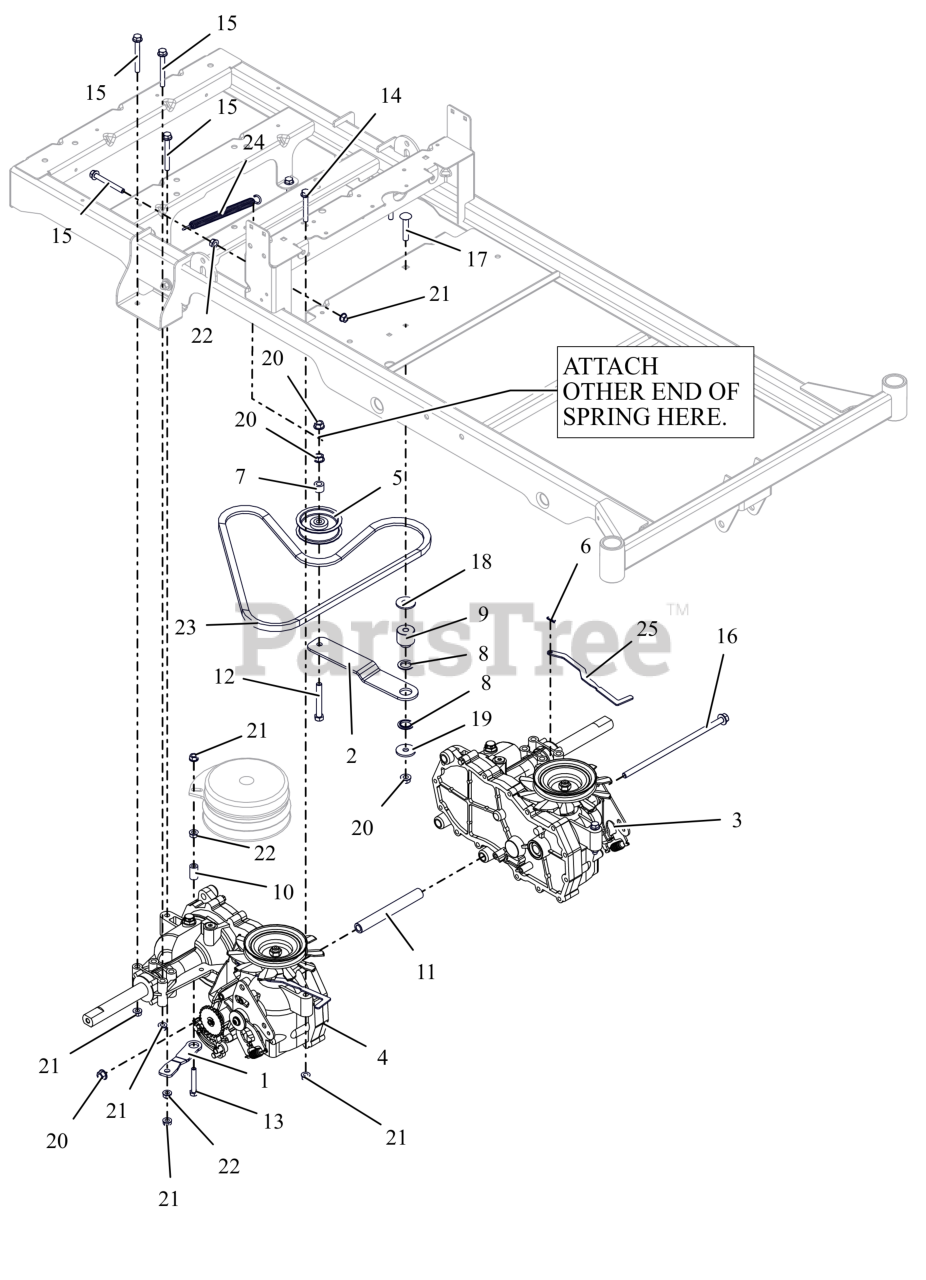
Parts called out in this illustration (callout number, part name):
1	BRKT, CLUTCH
2	IDLER ARM, GROUND DRIVE
3	TRANSAXLE- LH EZT D-SHAFT LONG
4	TRANSAXLE- RH EZT D-SHAFT LONG
5	PULLEY, ENGINE CLUTCH 03608
6	PIN, HAIR #178 .06X.77 ZCC
7	BSHG-SLV .391X.688X.52 PM
8	BUSHING, IDLER ARM
9	SPACER, GROUND DRIVE IDLER
10	SPACER, RUBBER 5/16 IDX1.0 LG
11	SPCR, TRANSAXLE .438 ID X .750 OD X 6.125 (BLACK)
12	BLT, HEX .38-16X2.75 G5 ZCC
13	BLT, HEX .31-18X2.00 G5 ZCC
14	BLT,HEX-FLG .31-18X2.25 G5 ZCC
15	BLT,HEX-FLG .31-18X2.75 G5 ZCC
16	BLT, HEX-FLG 0.375-16X9.75 GR5 ZC120
17	BLT,RHSSN.375-16X2.00 G5 ZCC
18	WSHR,FLT .563X1.375X.109 ZCC
19	WSHR,FLT .406X1.375X.135 ZCC
20	NUT-LK-CTR-FLG .375-16 GF ZCC
21	NUT,LK-CTR-FLG .31-18 GF ZCC
22	NUT,SPNLK-FLG .31-18 G5 ZCC
23	V-BELT, HA-RAW EDGE
24	SPRING, EXTENSION
25	BRKT, VALVE DUMP (BLACK)
